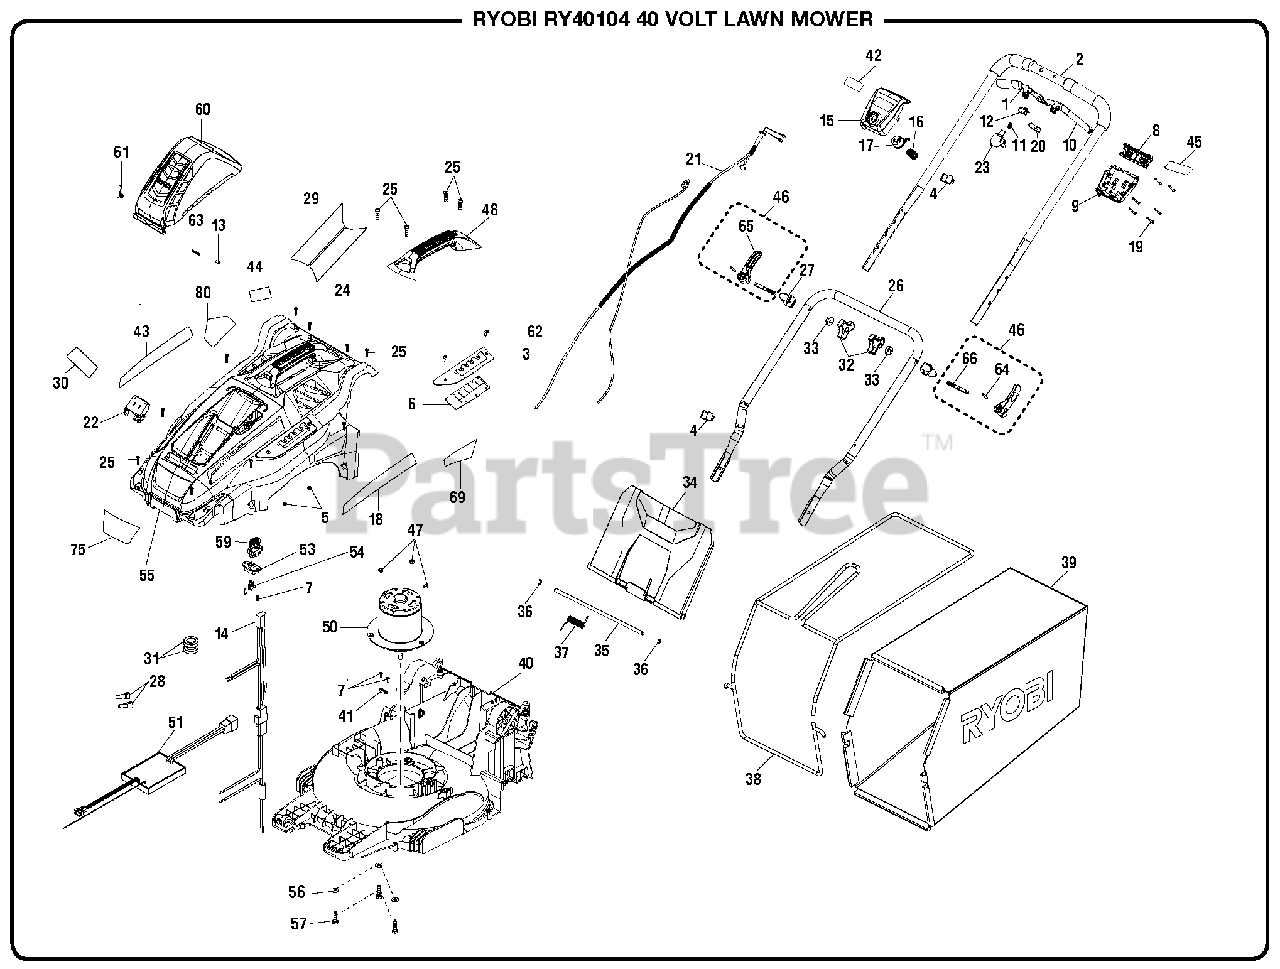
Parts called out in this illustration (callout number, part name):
1	Trigger Handle (Right Power Lever)
2	Upper Handle Assembly
3	Height Adjustment Plate
4	Cord Clamp
5	Lock Nut (M5)
6	Dust Gasket
7	Screw (M4 x 16, T20 Torx Hd.)
8	Lower Cover (Stain Handle)
9	Lower Cover (Trigger Housing)
10	Trigger Handle (Left Power Lever)
11	Compression Spring
13	Battery Door Axle
14	Terminal Block w/Leads
15	Upper Cover (Control Assembly)
16	Compression Spring
17	Start Button
18	Lithium Label (Left)
19	Screw (M4 x 30 mm, T15 Torx Pan Hd.)
21	Starter Cable (Long)
22	Battery Holder Assembly
23	Switch Holder
24	Warning Icon Label (Right)
25	Screw (M3.5 x 20 mm, T20 Torx Pan Hd.)
26	Lower Handle
27	Pressure Block
28	Wire Connector
29	Warning Icon Label (Left)
30	Start Key Label (Eng)
31	Ferrite Induct Ring
33	Block Washer
34	Rear Discharge Door
35	Rear Door Axle
36	Retaining Ring (E)
37	Torsion Spring (Rear Door)
38	Bag Frame
39	Bag
41	Cord Clamp
42	Ryobi Logo Label (Handle)
43	Lithium Label (Right)
44	Data Label
45	Starting Instructions Label
46	Handle Lock Assembly
47	Lock Nut (M6)
51	Soft Start Circuit Board
53	Key Holder
54	Key Receptacle
55	Deck Cover
56	Washer (OD15 x ID6 x 1t)
57	Bolt (M6 x 26 mm, Hex Hd.)
59	Start Key
60	Battery Cover
61	Torsion Spring (Battery Door)
62	Screw (M5 x 16 mm, Pan Hd.)
63	Compression Spring
64	Spring Pin
66	Quick Lock Press
69	Cut Diameter Label (Left)
75	Ryobi Logo Label (Front)
80	Cut Finger Label
